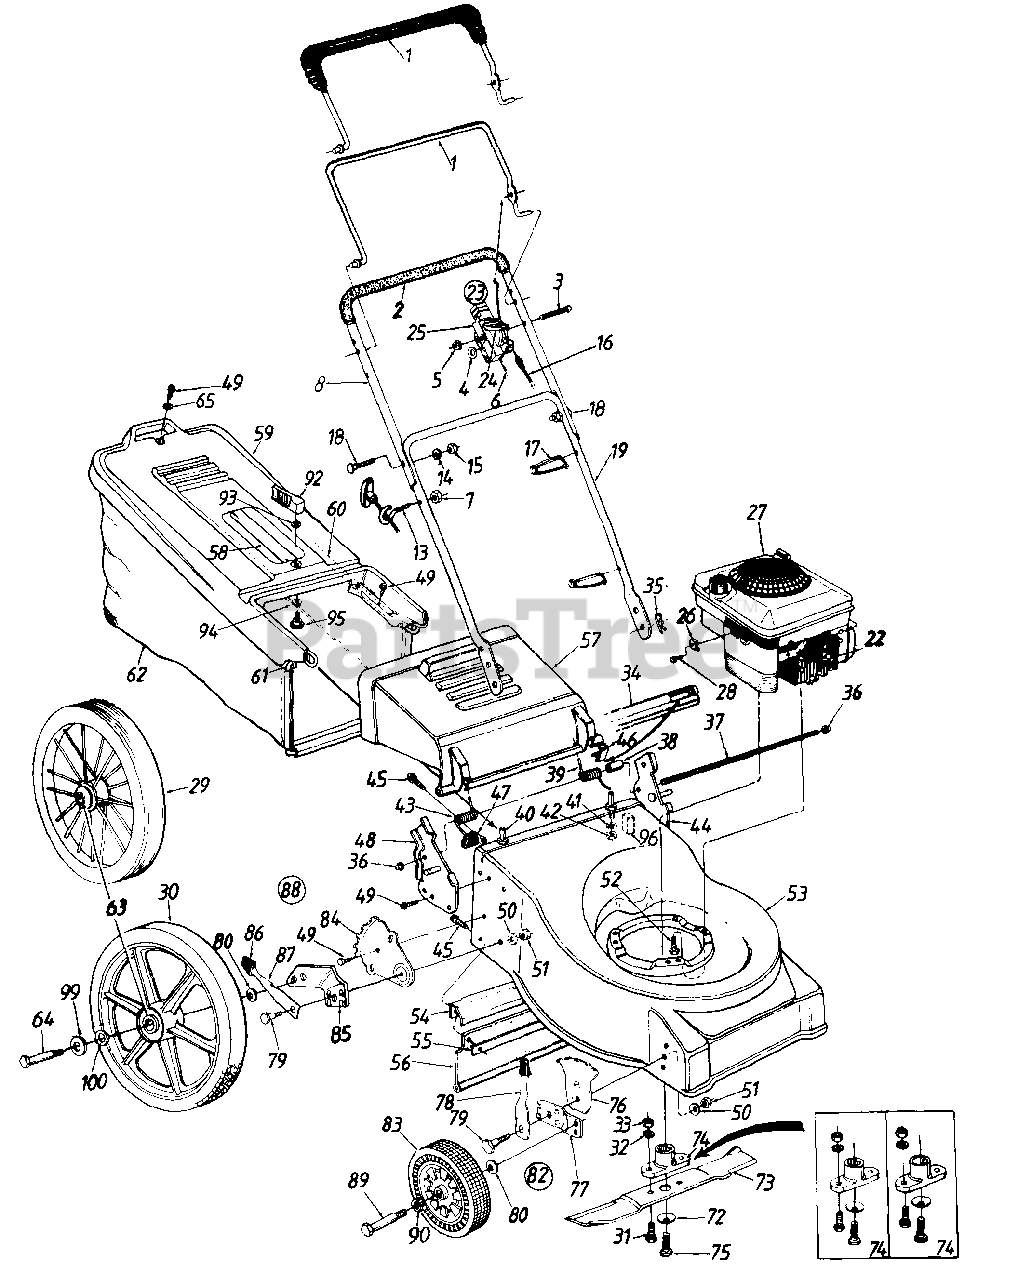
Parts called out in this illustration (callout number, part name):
2	Foam Grip
3	Oval C-Sunk Scr.
4	Spr. Wash. .66" I.D.
5	Hex L-Nut 1/4-20 Thd.
6	Throttle Cable - 55" (B&S)
7	Hex L-Nut 1/4-20 Thd.
14	L-Wash. 5/16" I.D.
15	Hex Nut 5/16-18 Thd.
16	Control Cable - 40.5" (B&S)
17	Cable Tie
18	Curved Carriage Bolt 5/16-18 x 1.38" Lg.
19	Lower Handle
22	Spark Plug Boot
24	Throttle Lever
25	Throttle Body
27	Engine
28	Hex Self-Tap Scr. #10-32 x .62" Lg. (B&S)
29	Wheel Ass'y. Comp. - Steel Rim
30	Wheel Ass'y. Comp. - Plastic Rim
31	Hex Bolt 3/8-24 x 1"
32	L-Wash. 3/8" I.D.
33	Hex Nut 3/8-24 Thd.
34	Seal - Extrusion
35	Int. Cotter Pin 5/16" Dia.
36	Cap Speed Nut
37	Hinge Pin 17.75" Lg.
38	Spacer .255" I.D.
39	Torsion Spring - L.H.
40	Shld. Pin 3/8-24 x 1.43" Lg.
41	L-Wash. 3/8" I.D.
42	Hex Jam Nut 3/8-24 Thd.
43	Torsion Spring - R.H.
44	Handle Brkt. Ass'y. - L.H.
45	Torx Mach. AB-Tap Scr. 1/4 x .62" Lg.
46	Deflector Plug
47	Corner Plug
48	Handle Brkt. Ass'y. - R.H.
49	Hex L-Wash. AB-Tap Scr. 1/4 x .62" Lg.
50	Bell-Wash. .39" I.D.
51	Hex Nut 3/8-16 Thd.
52	Hex L-Wash. Hd. Scr. 3/8-16 x 1" Lg.
57	Rear Chute Deflector
58	Hardtop Handle
59	Hardtop Bag Cover
60	Rear Catcher Frame
62	Grass Bag
63	Bearing (2 Per Wheel)
64	Shld. Bolt .5 Dia. x 2.62"
65	Fl-Wash. .281" I.D.
72	Bell-Wash. .46" I.D.
73	21" Blade
74	Blade Adapter Kit
75	Hex Bolt 7/16-20 x 1.5" Lg.
76	Height Adj. Plate
78	Spring Lever Ass'y. w/Knob
79	Shld. Bolt .50" Dia. x .357"
80	Bell-Wash..38" I.D. x .88" O.D.
82	Height Adj. Ass'y. Comp. - R.H.
83	Wheel Ass'y. Comp. Diamond Tread (7")
84	Index Plate
85	Pivot Bar - R.H.
86	Spring Lever Knob
87	Spring Lever
88	Rear Height Adj. Ass'y. Comp. - R.H.
89	Axle Bolt
90	Wave Wash. .53" I.D. x .78" O.D.
92	Grass Catcher Locking Knob
93	Internal L-Wash. 1/4" I.D.
94	Wave Washer 3/8" I.D.
95	Shld. Bolt .342" Dia. x .268"
99	Fl-Wash. .51" I.D. x 1.373"
100	Spr. Wash. .5" I.D. x 1" O.D.
